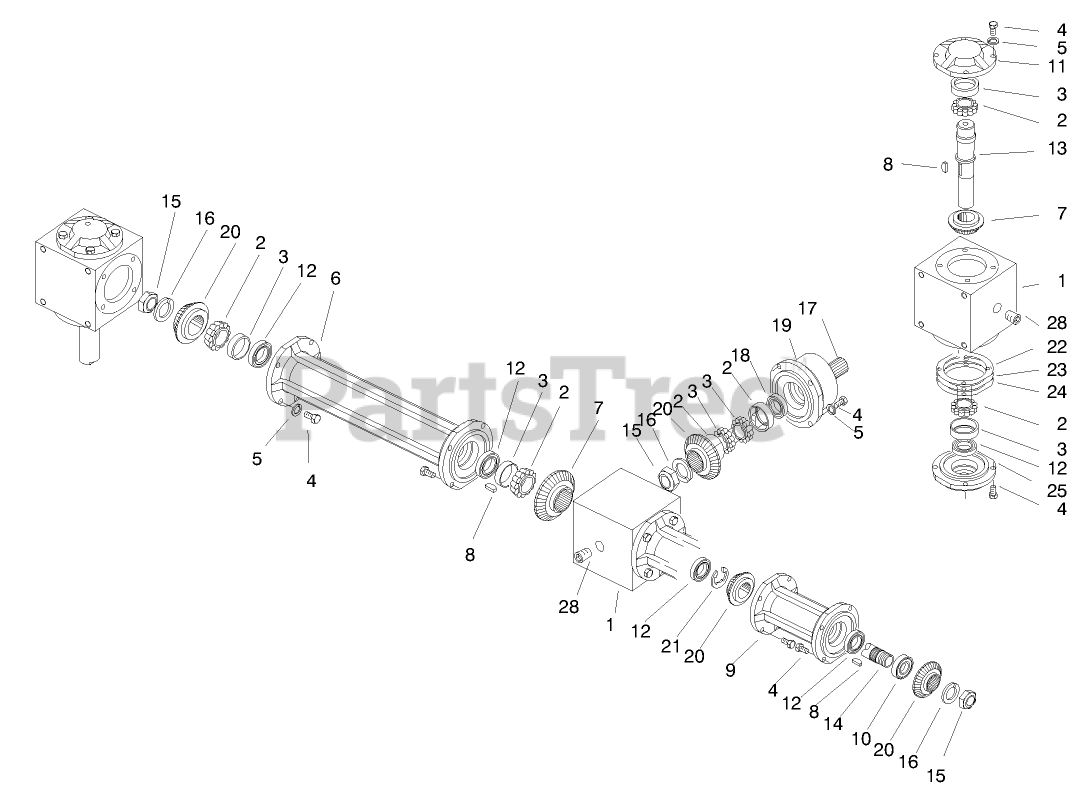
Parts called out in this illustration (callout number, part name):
1	HOUSING
2	BEARING - CONE
3	Cup
4	SCREW - HH
5	WASHER - LOCK
6	Connector-Hub
7	Gear-RH
9	Connector-Hub
10	BEARING - BALL
11	CAP - BLANK
12	Seal
13	Shaft-Thru
14	SHAFT
15	NUT - LOCK
16	WASHER - LOCK
17	SHAFT - HUB
20	PINION - LH
21	RING - RETAINING
22	Gasket-.015
23	Gasket-.005
24	GASKET - .003
25	CAP - THRU
26	I.d. Tag
27	I.d. Tag Cover
28	PLUG (OBS, C/R TO 281-10)
